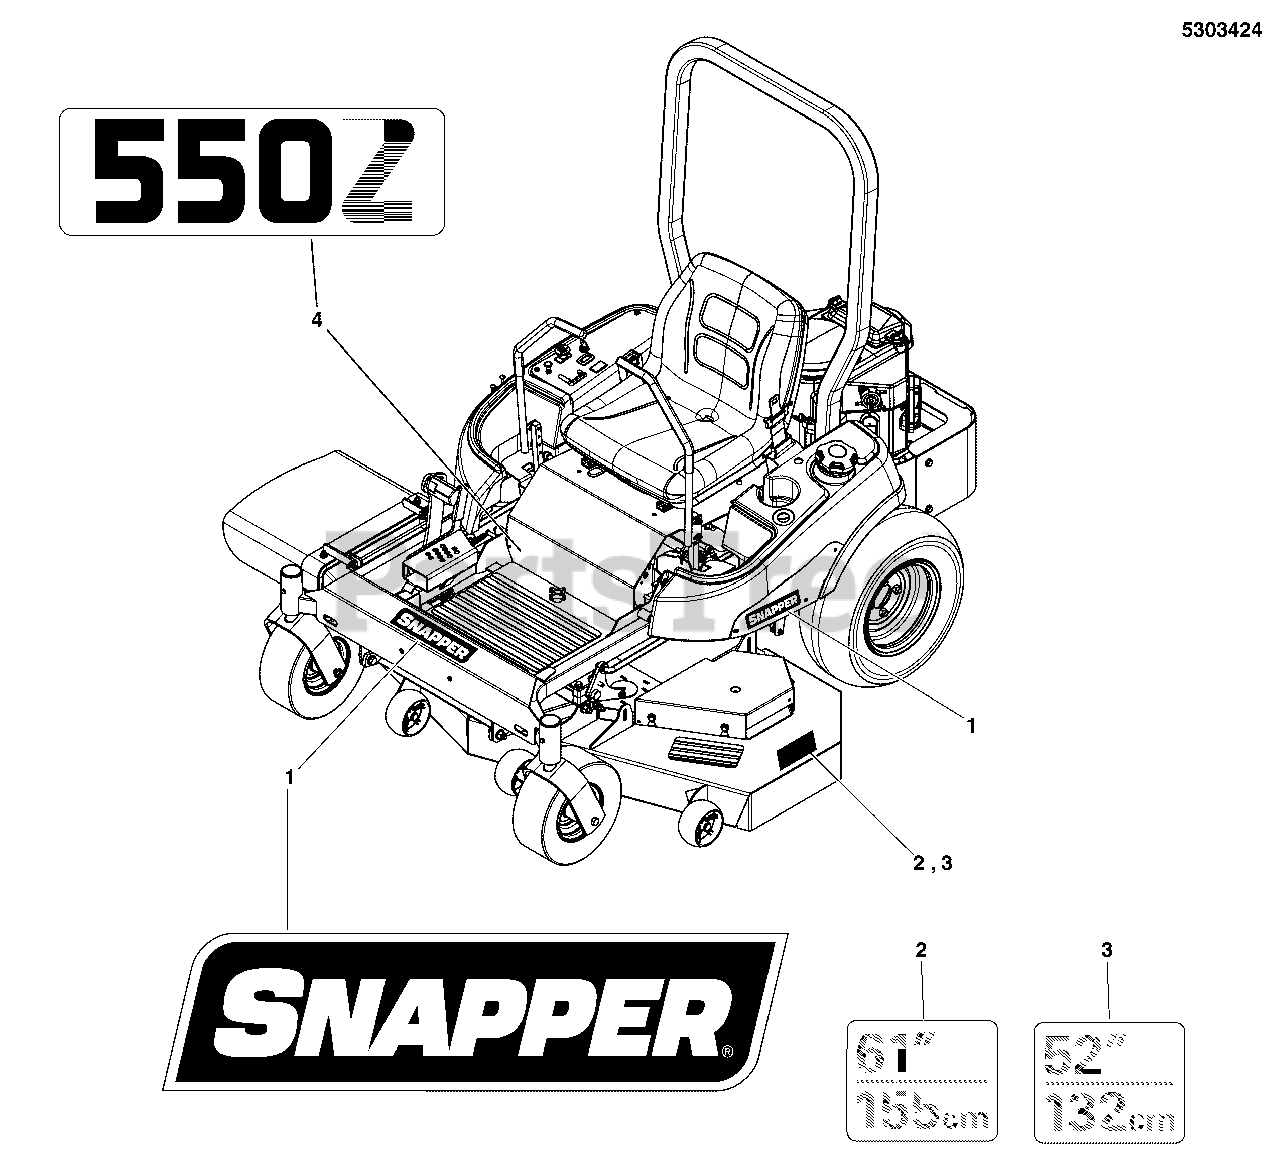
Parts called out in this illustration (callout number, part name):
1	DECAL, Logo, Snapper
2	DECAL, MOWER WIDTH 61 IN/155 CM
3	DECAL, MOWER WIDTH 52 IN/132 CM
4	DECAL, MODEL SERIES, 550Z
